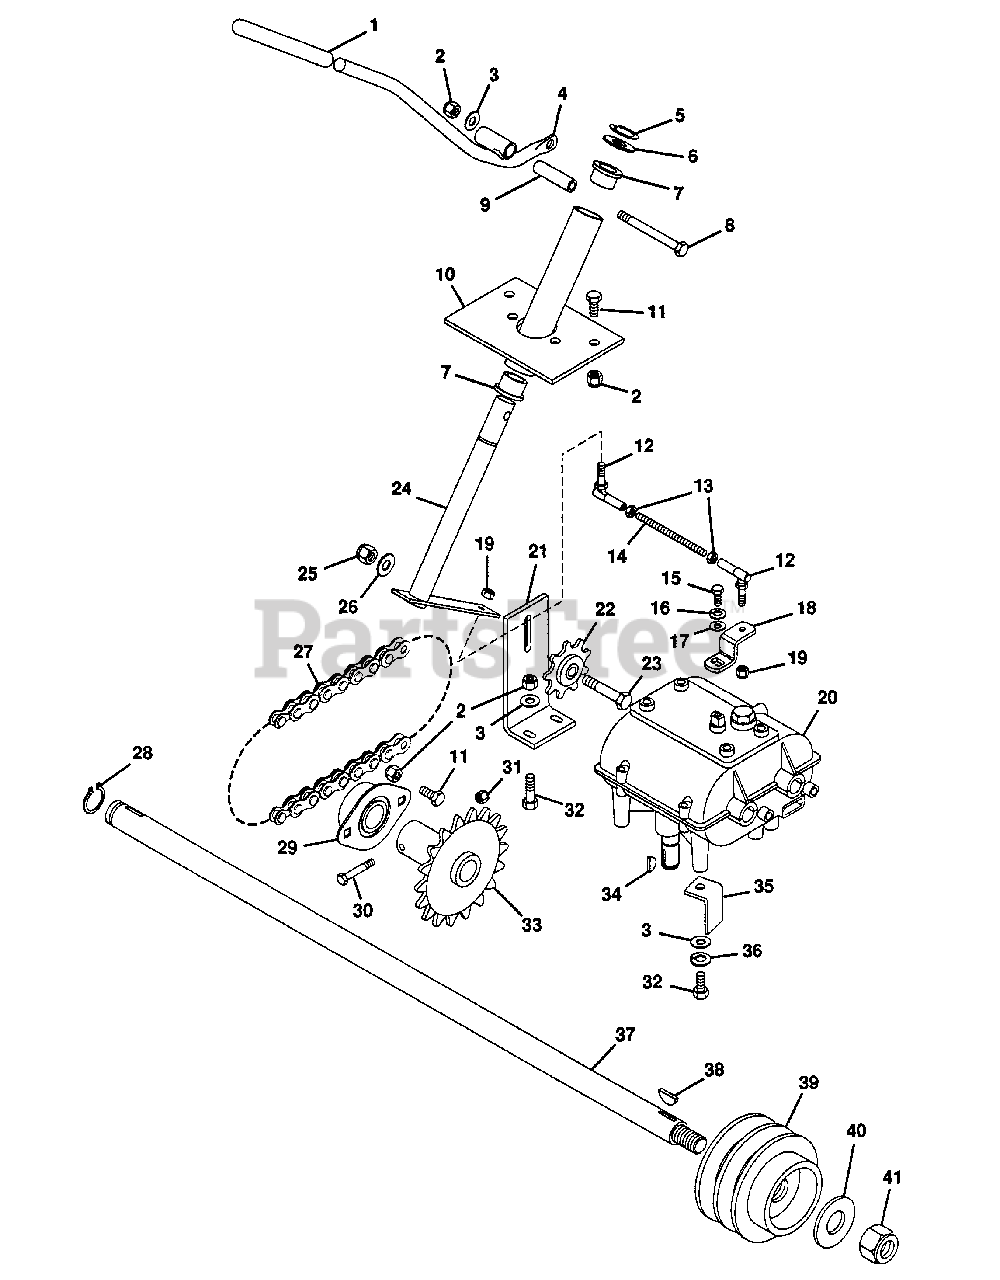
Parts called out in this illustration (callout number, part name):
1	GRIP, PTO LEVER
2	NUT, LOCK 5/16-18
3	WASHER, FLAT .344X.688X.065
4	WELDMENT, SHIFT LEVER
5	RING, RETAINING
6	RACE, BEARING THRUST
7	BUSHING, FLANGE NYLON
8	BOLT, HEX 5/16-18X2.75
9	BUSHING, ST. .328X.497X1.53 STL.
10	WELDMENT, SHIFTER TUBE
11	BOLT, HEX 5/16-18X.75
12	BALL JOINT, DISCONNECTING
13	NUT, HEX 1/4-28
14	ROD, TRANS. SHIFTER
15	BOLT, HEX 1/4-28X.50
16	WASHER, LOCK 1/4
17	WASHER, FLAT .281X.625X.065
18	ARM, TRANS. SHIFT
19	NUT, LOCK 1/4-28
20	TRANSMISSION, PRO LINE
21	BRACKET, IDLER SPROCKET
22	SPROCKET, IDLER
23	BOLT, HEX 3/8-16X1.75
24	WELDMENT, SHIFTER SHAFT
25	NUT, LOCK 3/8-16
26	WASHER, FLAT .406X.812X.065
27	CHAIN, NO. 40
28	RING, RETAINING .984 SHAFT
29	BEARING, FLANGED 1.00 SHAFT
30	BOLT, HEX 1/4-20X2.00
31	NUT, LOCK 1/4-20
32	BOLT, HEX 5/16-18X1.00
33	WELDMENT, 28T .5 PITCH SPROCKET
34	KEY, WOODRUFF .187X.750 HARD #9
35	GUIDE, V-BELT
36	WASHER, LOCK 5/16 REG.
37	SHAFT, JACK
38	KEY, WOODRUFF 1/4X1.00 HARD #15
39	PULLEY, JACK-SHAFT
40	WASHER, FLAT .813X1.37X.100
41	NUT, LOCK 3/4-10 L.T.
